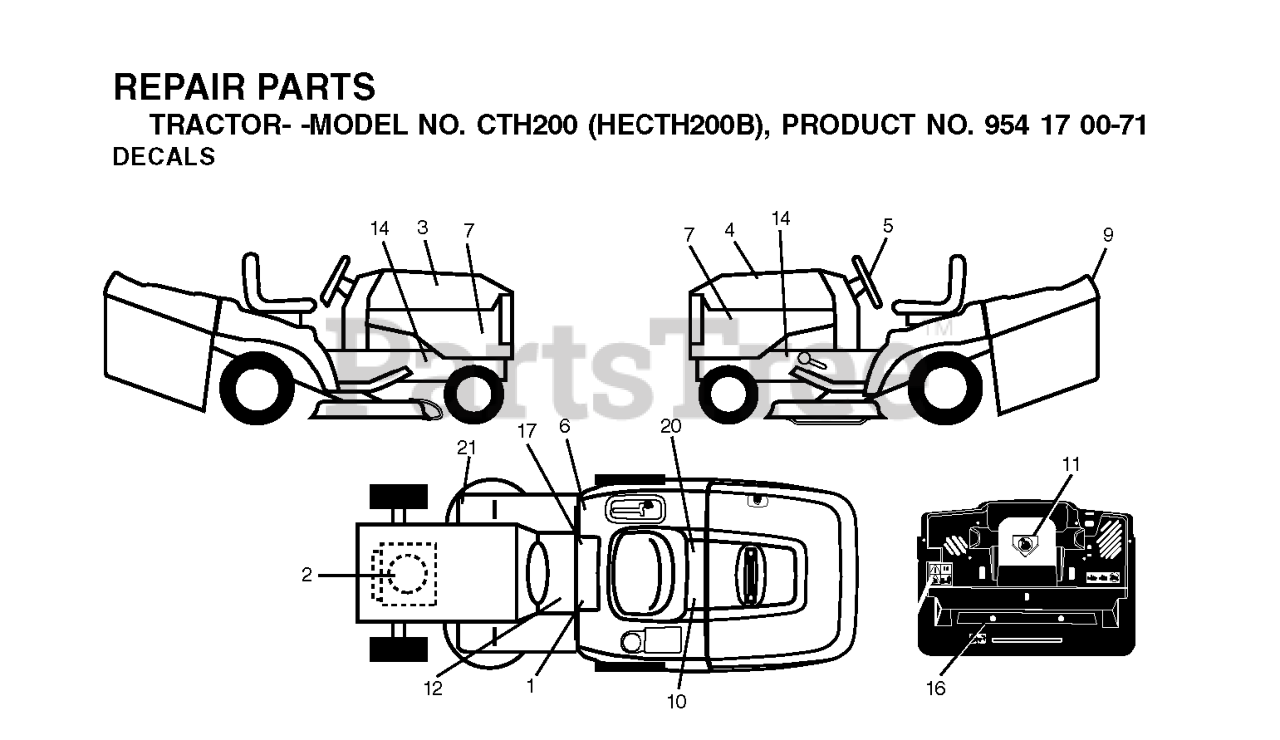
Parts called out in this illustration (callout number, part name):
1	DECAL READ OWNER'S MAN SYMS
5	DECAL.WHEEL.STEERING.HUSQ.PERM
6	Decal, Fender 100 DB/CE
7	DECAL PNL SIDE
9	DECAL FENDER HUSQ
10	DECAL BTRY SYMBOLS
11	DECAL.INTERNATIONL.CUTFINGER
12	DECAL
16	DECAL
17	DECAL PARK BRAKE
20	DECAL.BYPASS.FENDER.CRD.LT.YT
21	DECAL
